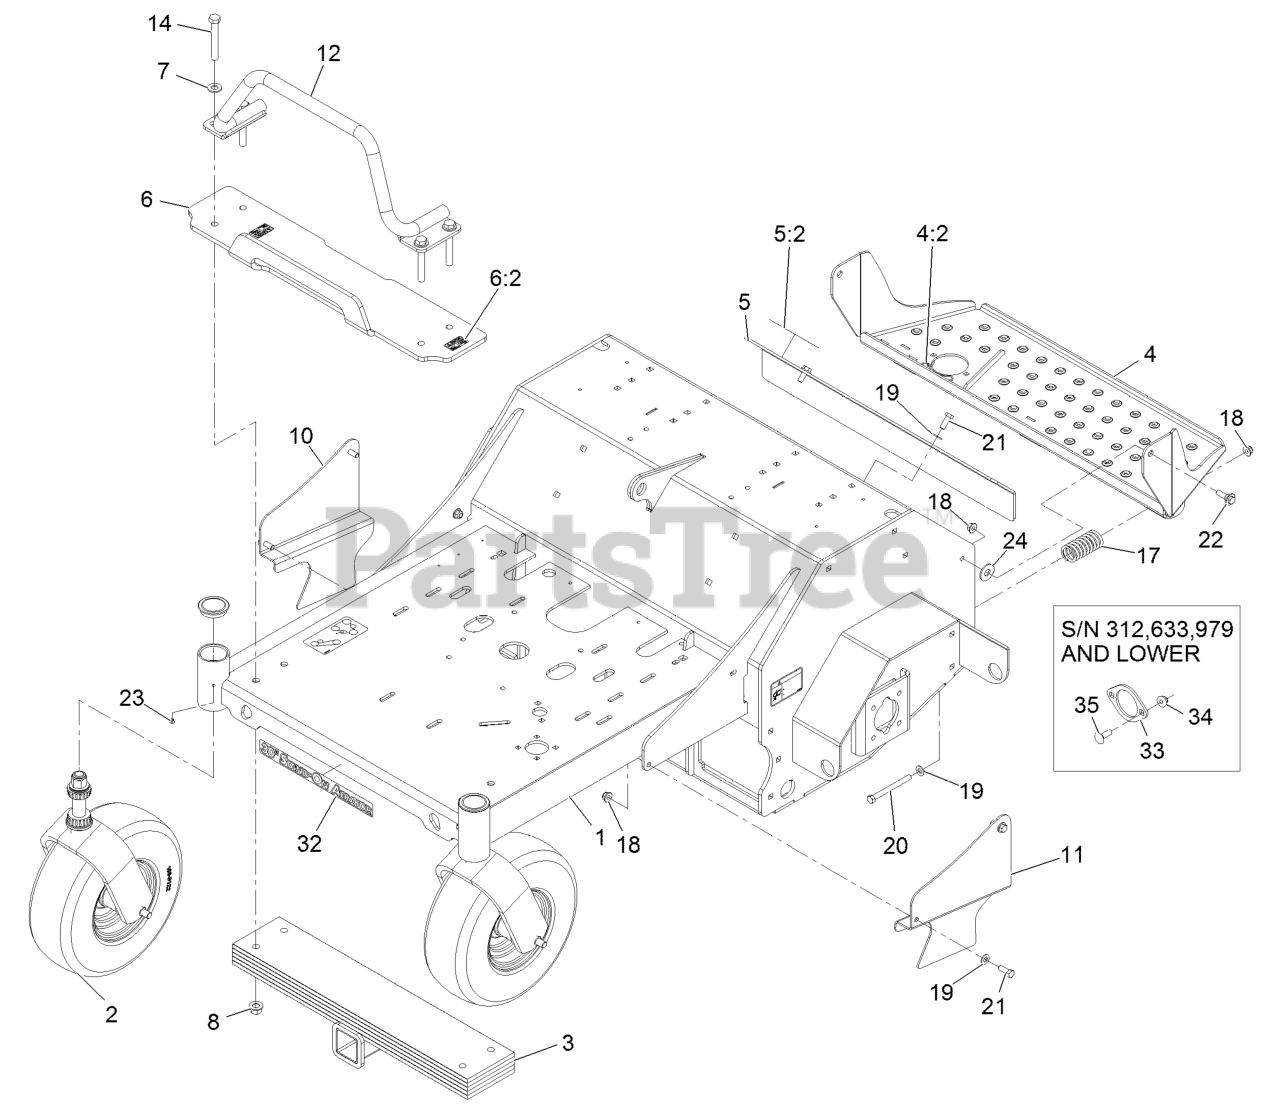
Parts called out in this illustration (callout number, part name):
1	Main Frame And Decal Asm
2	Front Caster Asm W/Fork
4	PLATFORM ASM W/DECALS
4:2	DECAL-TINE GROUND ENGAGEM
5:2	DECAL-TINE GROUND OPERATI
6	WEIGHT MOUNT PLATE ASM
6:2	DECAL-CAUTION
7	WASHER-FLAT
8	Nut-Lock 1/2-13
10	GUARD-CHAIN, RH
11	GUARD-CHAIN, LH
12	GUARD-MUFFLER
14	SCREW-HH
17	SPRING-COMPRESSION
18	NUT-HF, NI
19	WASHER-FLAT
20	SCREW-HH
21	SCREW-HH
22	SCREW-SHOULDER, HWH
24	WASHER-FLAT
32	DECAL-STAND-ON AERATOR 30
33	RETAINER-SPRING
35	BOLT-CARR
